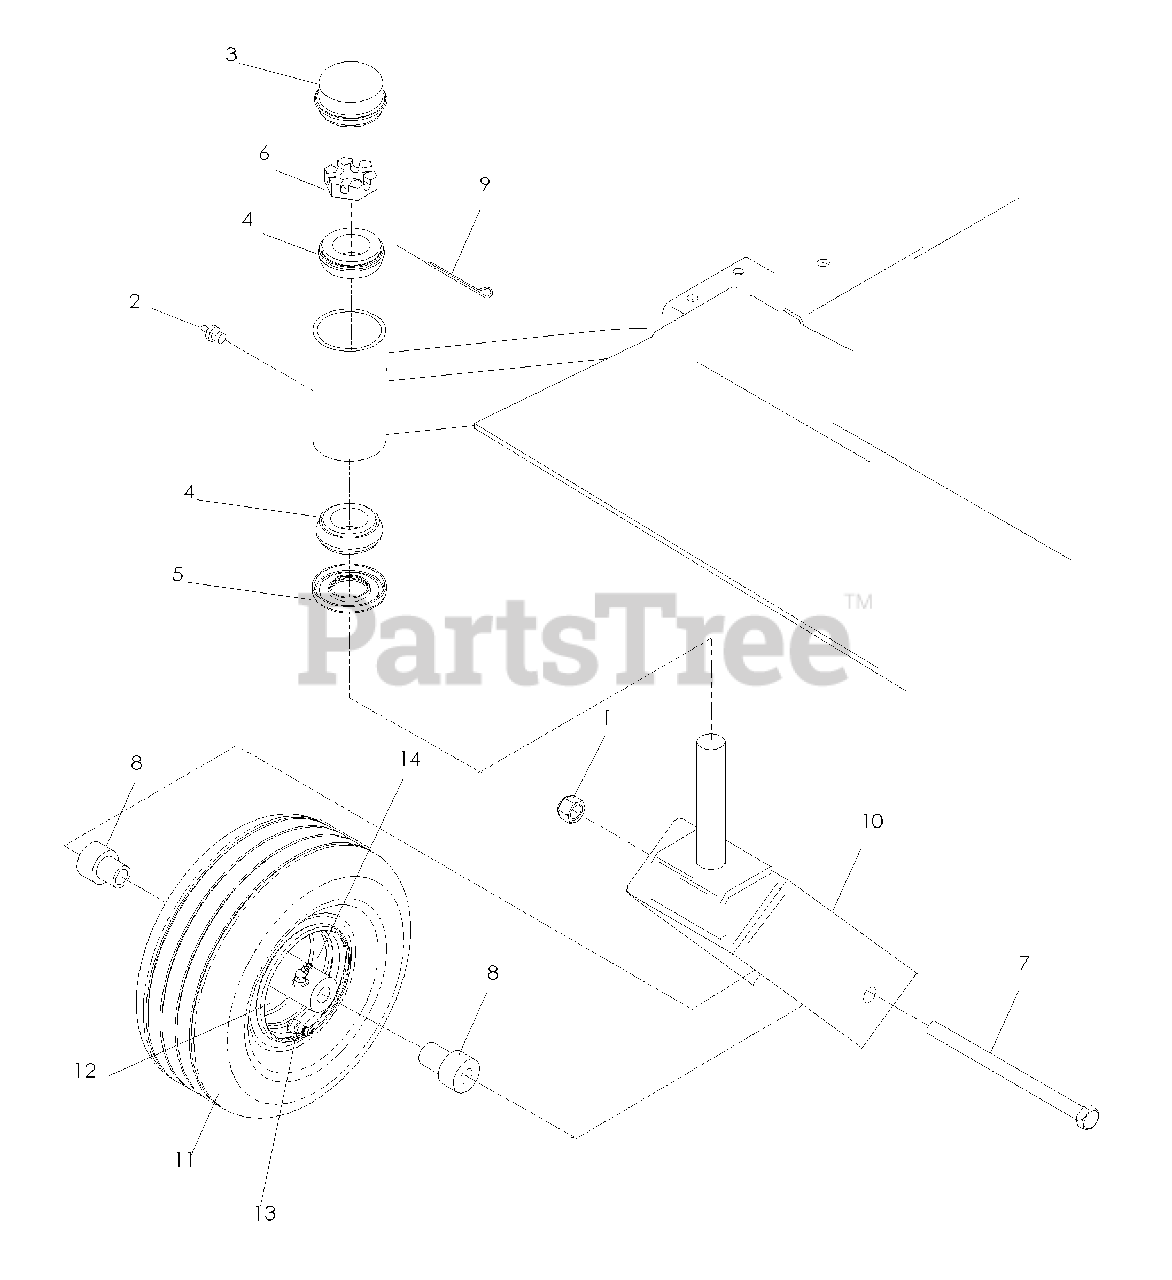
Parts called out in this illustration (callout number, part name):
1	NUT 1/2-13 HEX NYLOC
3	CAP, GREASE
4	BEARING, TAPERED
6	NUT 1-14, SLOTTED JAM
7	HCS 1/2-13 x 9 1/2
9	PIN, COTTER 1/8 x 2
10	CASTER YOKE
11	TIRE, COMPLETE
13	VALVE STEM
14	ZERK
